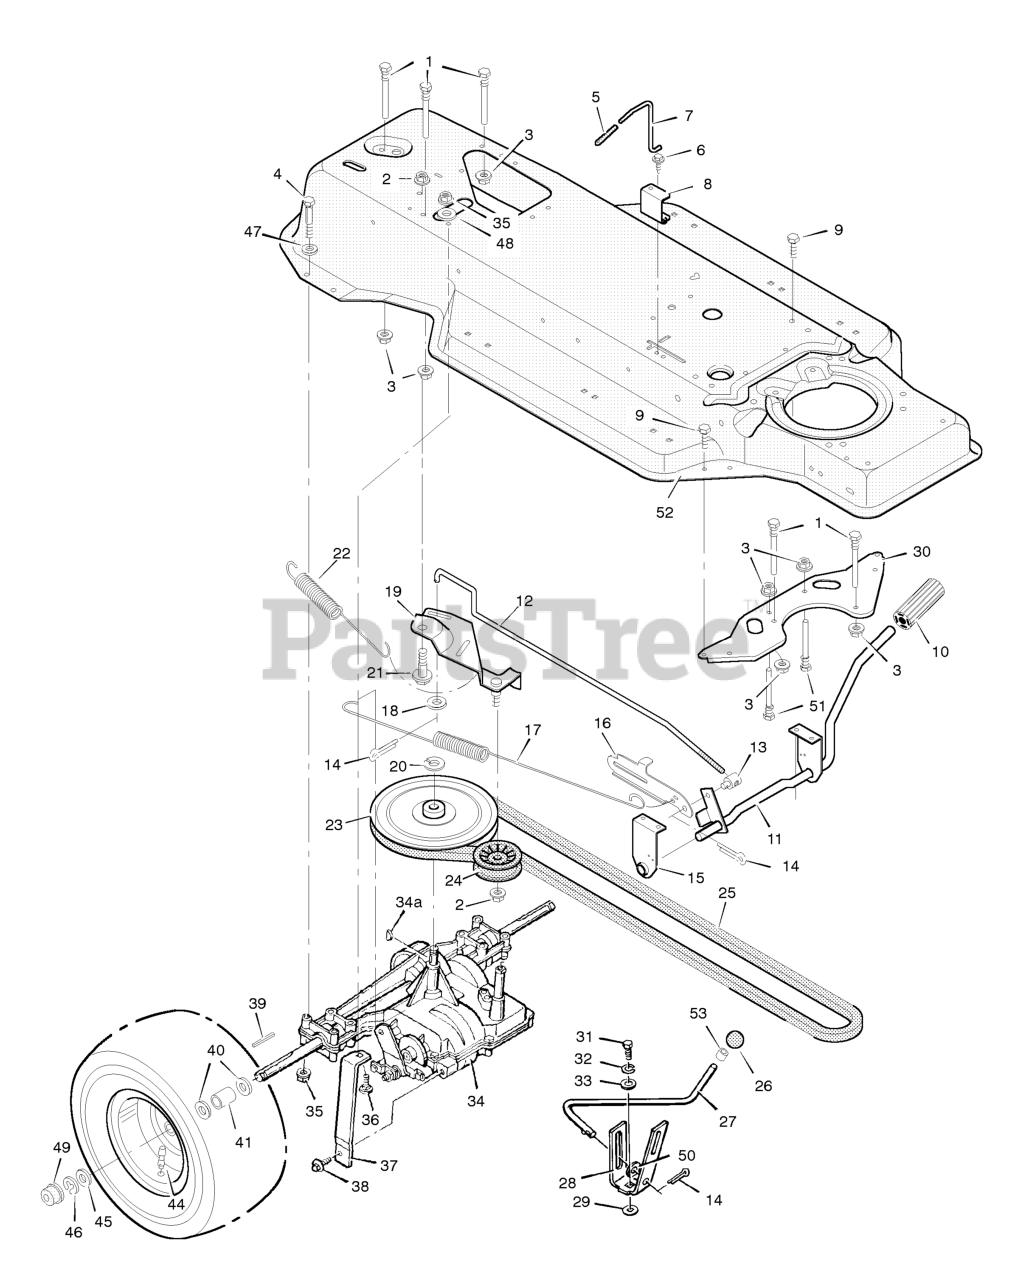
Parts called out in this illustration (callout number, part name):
1	Guide, Belt
2	Locknut, Flange
3	Nut, Flange
4	Bolt, Hex
7	Rod, Control
8	Guide, Bracket
10	Clutch and Brake Pedal
11	Lever Assembly
12	Rod, Clutch
13	Nut, Adjustable
14	Pin, Cotter
15	Bracket, Support
16	Latch, Park Brake
17	Spring, Brake Extension
18	Washer
19	Bracket Assembly, Idler
20	Ring, Retainer
21	Bolt, Shoulder
22	Spring, Drive Extension
23	Pulley, Motion Drive
24	Pulley, Backside Idler
25	Belt, Motion Drive
26	Knob, Shift Lever
27	Lever, Shift
28	Yoke, Shift
30	Plate, Belt Guide
31	Bolt, Hex
32	Lockwasher
34	Transaxle, Peerless **
34A	Woodruff Key No. 9
35	Nut, Flange
36	Bolt, Carriage
37	Support, Transaxle
39	Key, Square
41	Spacer, Transaxle
42	Tire *
43	Wheel & Tire Assembly
44	Stem, Valve
47	Washer
49	Hub Cap
50	Washer
51	Guide, Belt
52	Frame Assembly
53	Ring, Tolerance
